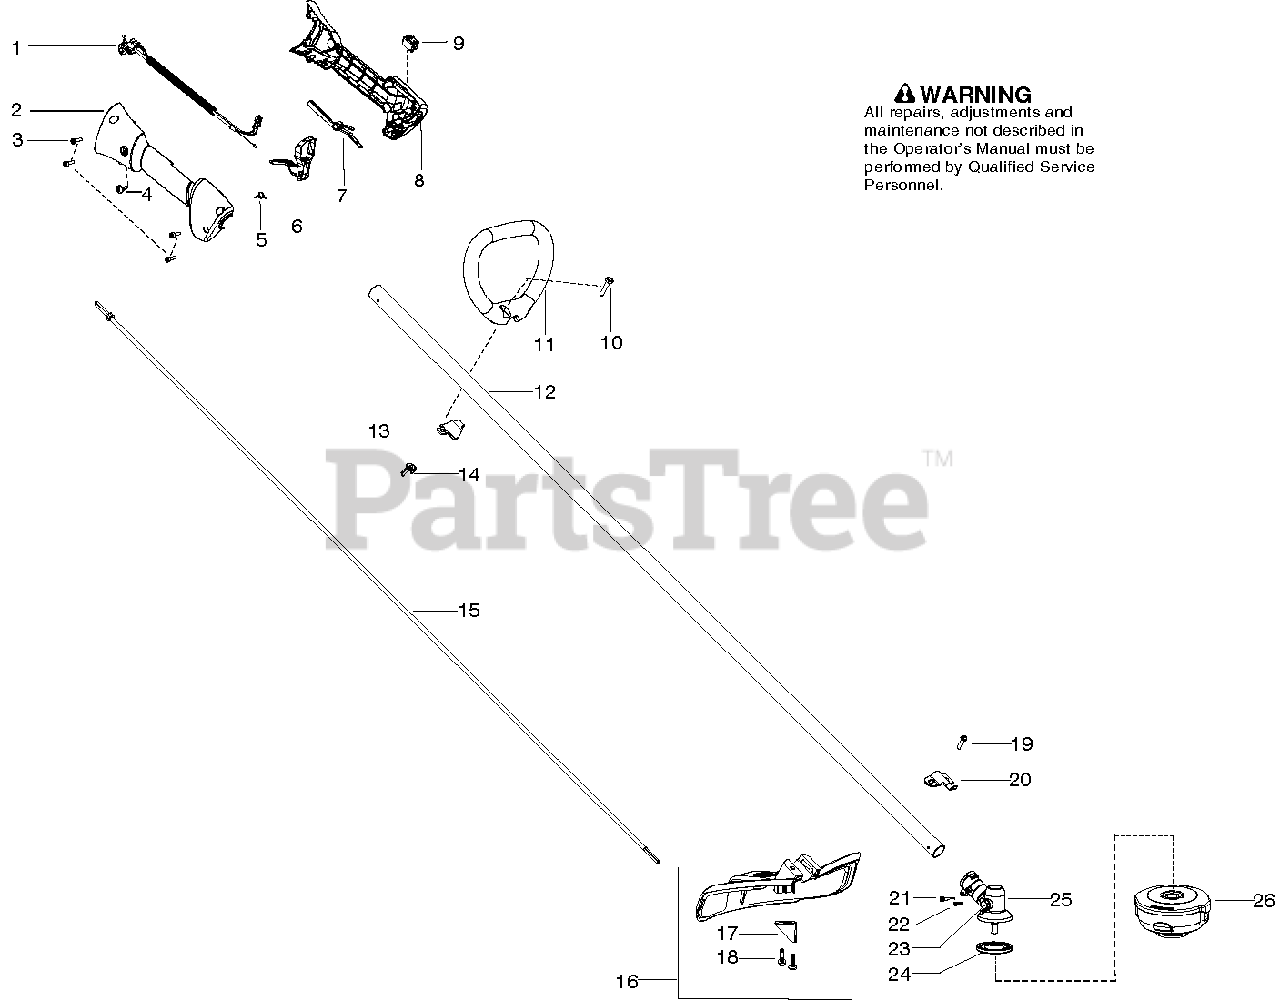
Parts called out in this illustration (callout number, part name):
1	ASSY THROTTLE
2	HOUSING RIGHT
5	SPRING TRIGGER
7	THROTTLE LOCKOUT
8	HOUSING THROTTLE LH
10	BOLT, TYPE 2
11	HANDLE ASSIST
12	KIT DRIVESHAFT SERVICE
13	CLAMP ASSIST HANDLE
14	WINGNUT, TYPE 2
15	FLEXSHAFT 57"
17	LINE CUTTER
18	SCREW 10-14X3/4 PLASTITE
19	SCREW 8-32 X 16.51 TT SC TRX
20	BRACKET SHIELD STRAIGHT SHAFT
21	Screw, 8-32 X 16.51
22	SCREW 8-32 X 16.51 TT SC TRX
24	DRIVE DISC
25	ASSY GEARBOX
26	T25 TRIM HEAD 10MM LH
